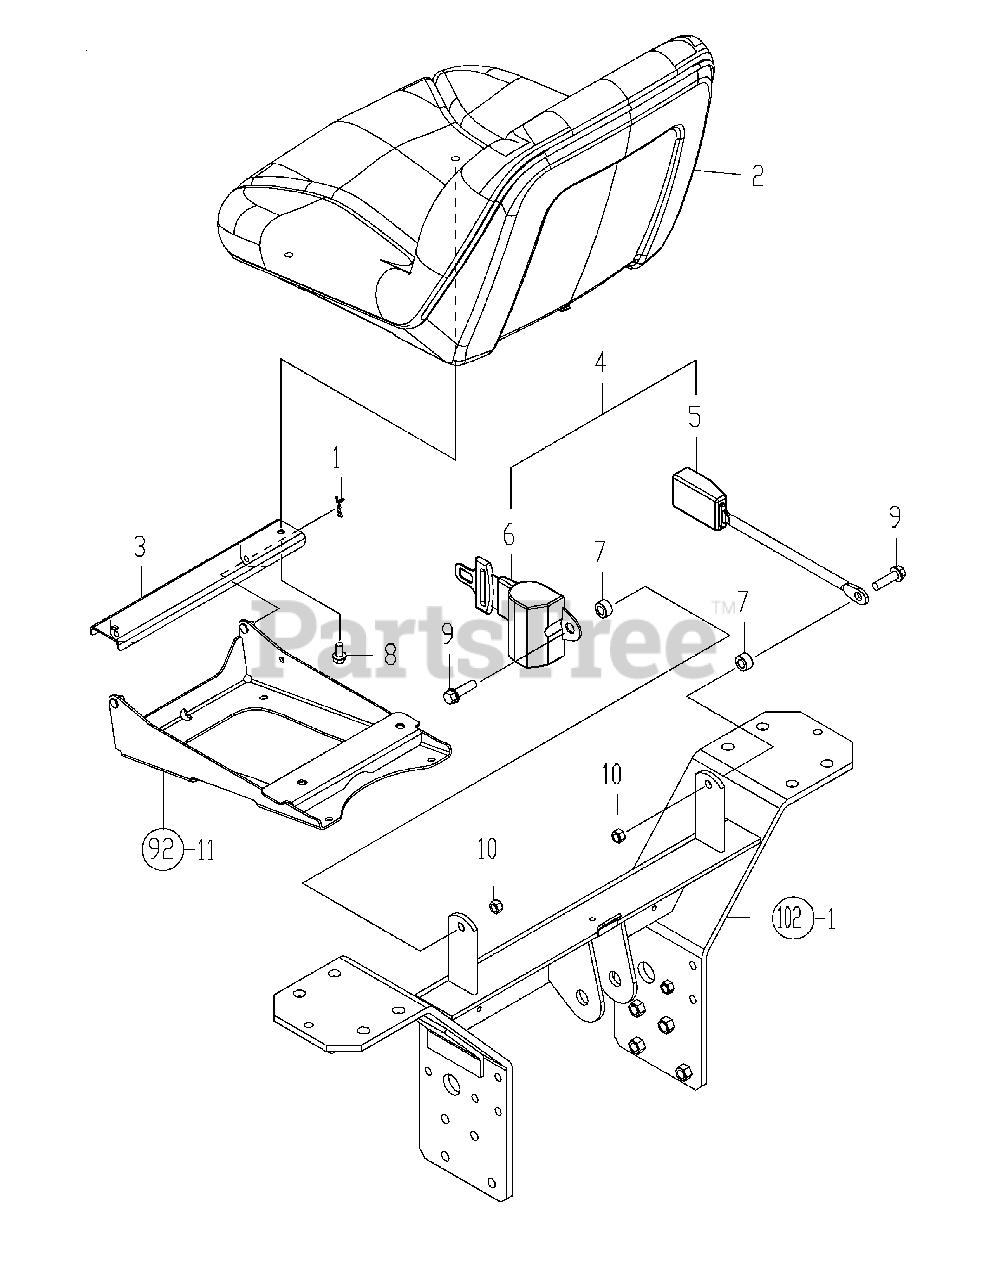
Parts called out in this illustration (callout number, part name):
2	SEAT ASSY, OPERATOR
3	HINGE, SEAT CMP
4	BELT,SAFETY CMP
7	COLLAR,SEAT BELT
